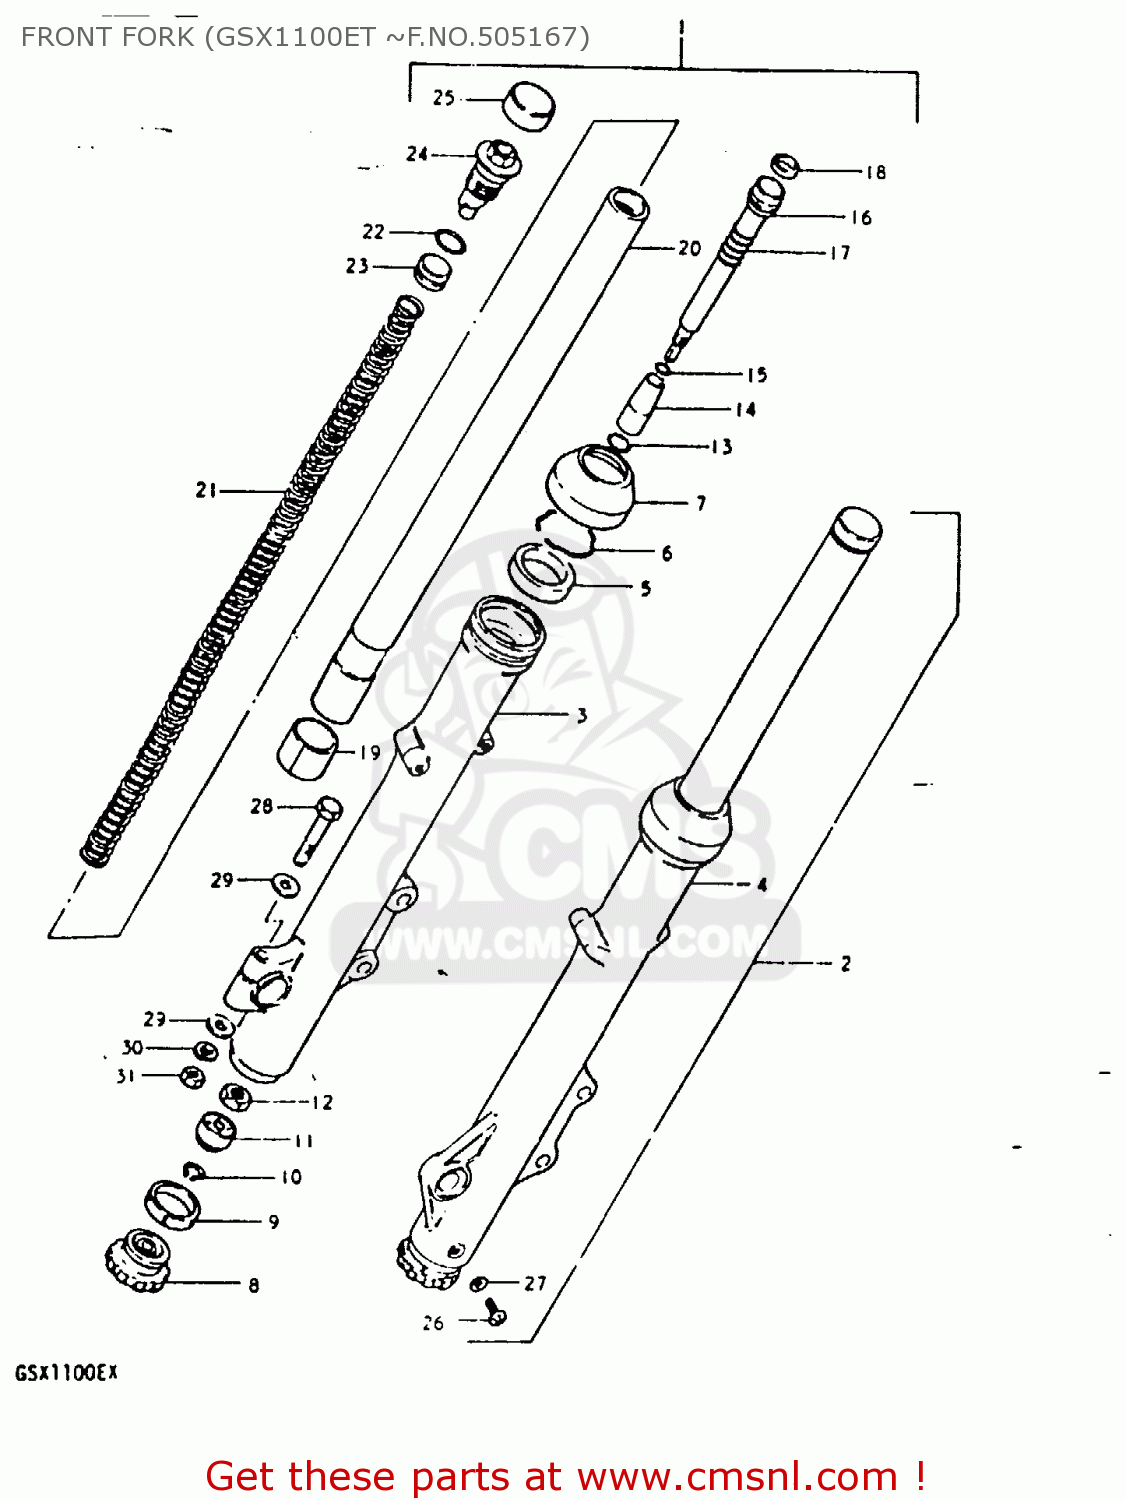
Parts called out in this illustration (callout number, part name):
1	DAMPER ASSY, RH
2	DAMPER ASSY, LH
3	OUTER TUBE, RH
4	OUTER TUBE, LH
5	OIL SEAL,FRONT FORK
6	RING,STOPPER
7	SEAL,DUST
8	HANDLE
9	RING
10	CIRCLIP
11	DETENT
12	NUT
13	O RING
14	PIECE, OIL LOCK
15	O RING
16	CYLINDER
17	SPRING,FORK REBOUND
18	RING,PISTON
19	PISTON
20	INNER TUBE
21	SPRING
22	O-RING
23	PISTON,FREE
24	CAP
25	CAP
26	SCREW
27	GASKET,DRAIN,PLUG (NAS)
28	BOLT 8X50
29	WASHER
30	WASHER,LOCK,8.
31	NUT
